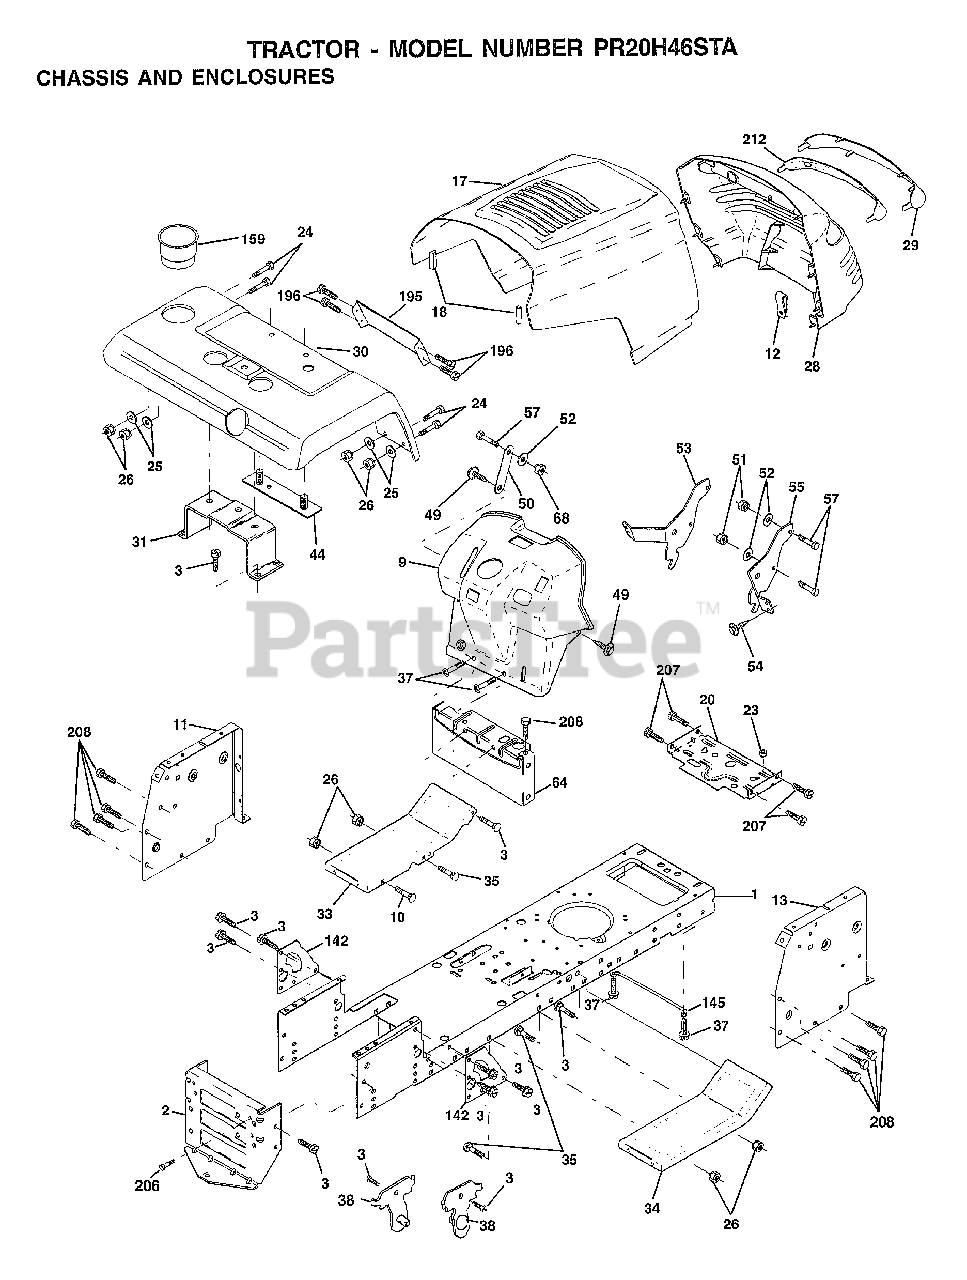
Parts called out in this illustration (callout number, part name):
1	CHASSIS
2	DRAWBAR
3	SCREW
11	PANEL DASH
12	CLIP.TINNERMAN
13	PANEL DASH
17	"HOOD W/TRIM,MS428"
20	"PLATE-MTG,BATT/FU"
24	BOLT
25	WASHER
26	NUT
28	GRILLE
29	LENS
31	BRKT.ASM.FENDER
33	FOOTREST PNT LH
34	FOOTREST.RH.LT/GT
35	BOLT
37	SCREW LT
38	BRKT ASM PIVOT MOWER REAR
44	STRAP ASM FENDER
49	SCREW HEX CRT
50	BRACE SUPT DASH
51	NUT
52	WASHER
53	BRACKET.GRILLE.LH
54	SCREW.HEX.WS.HD
55	BRACKET.GRILLE.RH
64	DASH-LOWER
68	NUT
142	PLATE.REINFORCEMENT
159	CUPHOLDER.YTGT
195	PANEL PNT FENDER YT/GT
196	SCREW CRT
206	BOLT SHOULDER
207	SCREW
208	SCREW
212	INSERT LENS REFLECT
